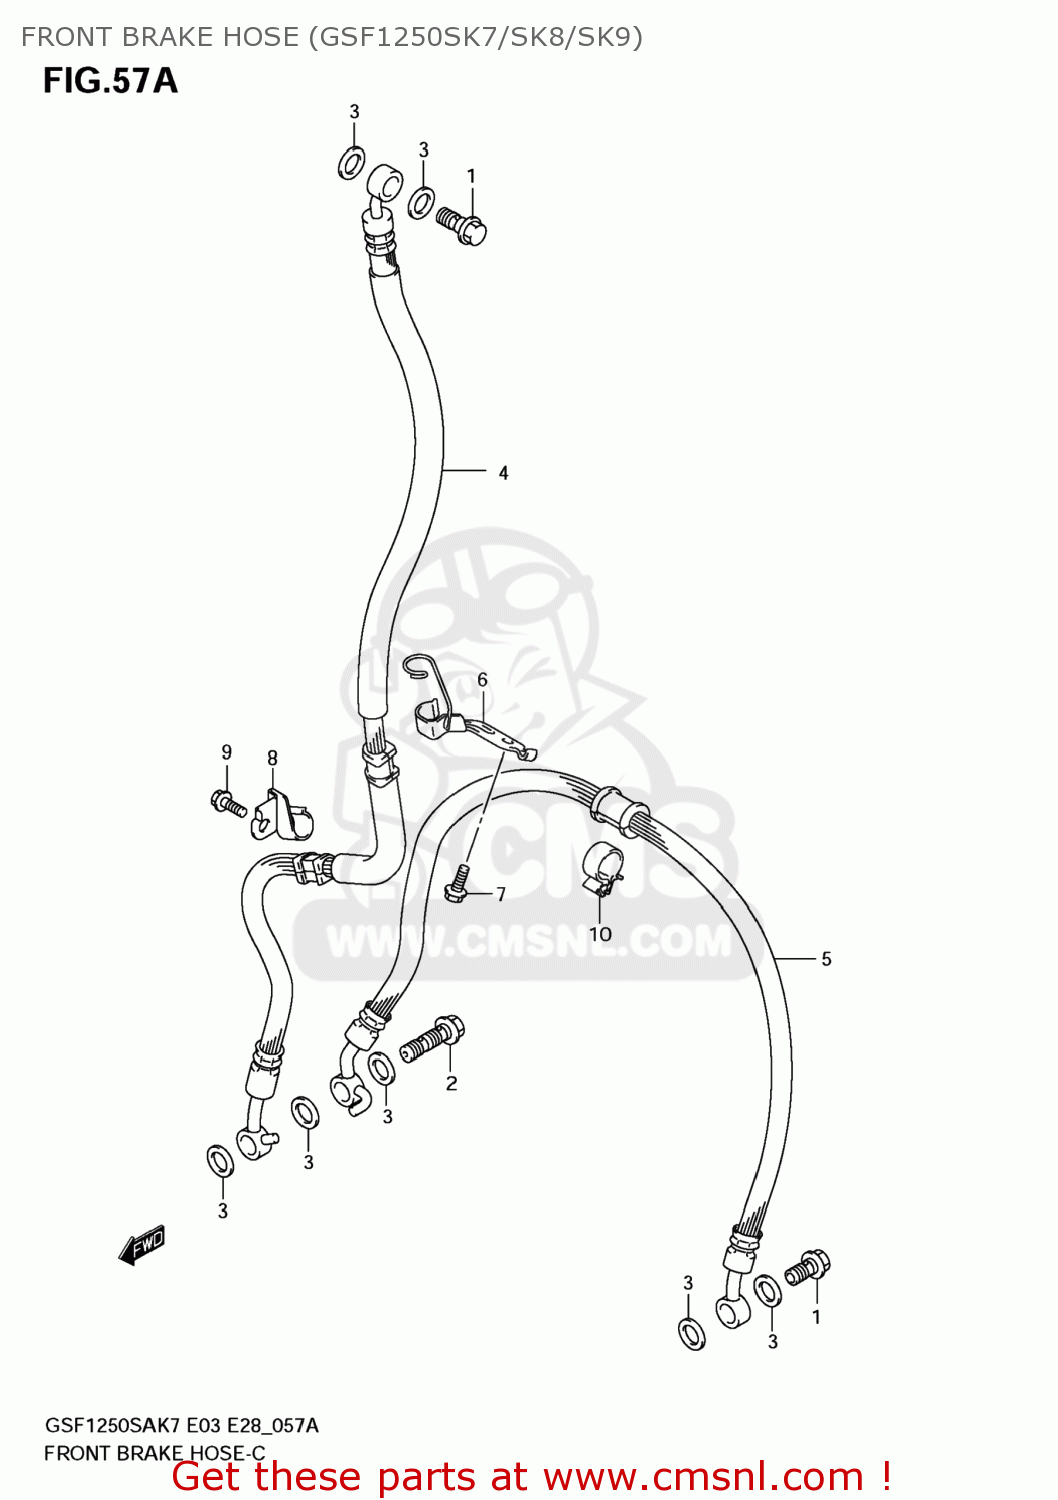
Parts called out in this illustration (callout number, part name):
1	BOLT UNION
2	BOLT UNION
3	WASHER(10X15X1.5)
4	HOSE,FR BRAKE NO.1
5	HOSE,FR BRAKE NO.2
6	CLAMP,FR BRAKE HOSE NO.1
7	BOLT
8	CLAMP,FR BRAKE HOSE NO.2,R
9	BOLT
10	CLAMP
